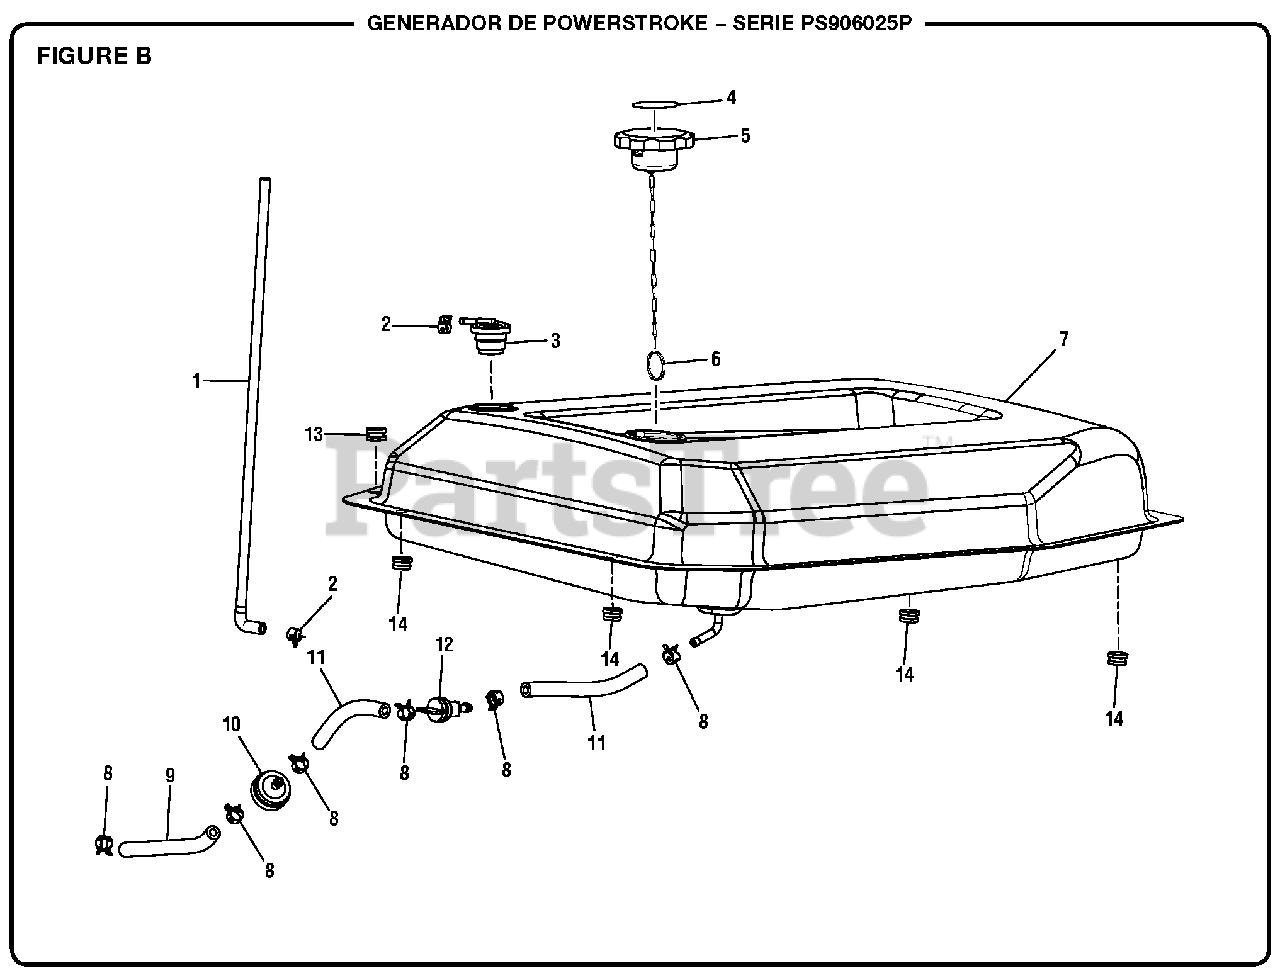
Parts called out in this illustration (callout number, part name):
1	Vapor Hose
2	Clamp (7/16 in.)
3	Fuel Tank Vapor Vent
4	Fuel Stabilizer Label
6	Ring Clip
7	Fuel Tank
8	Clamp (1/2 in.)
9	Fuel Hose
10	Fuel Filter
11	Fuel Hose
12	Fuel Shut Off Valve
